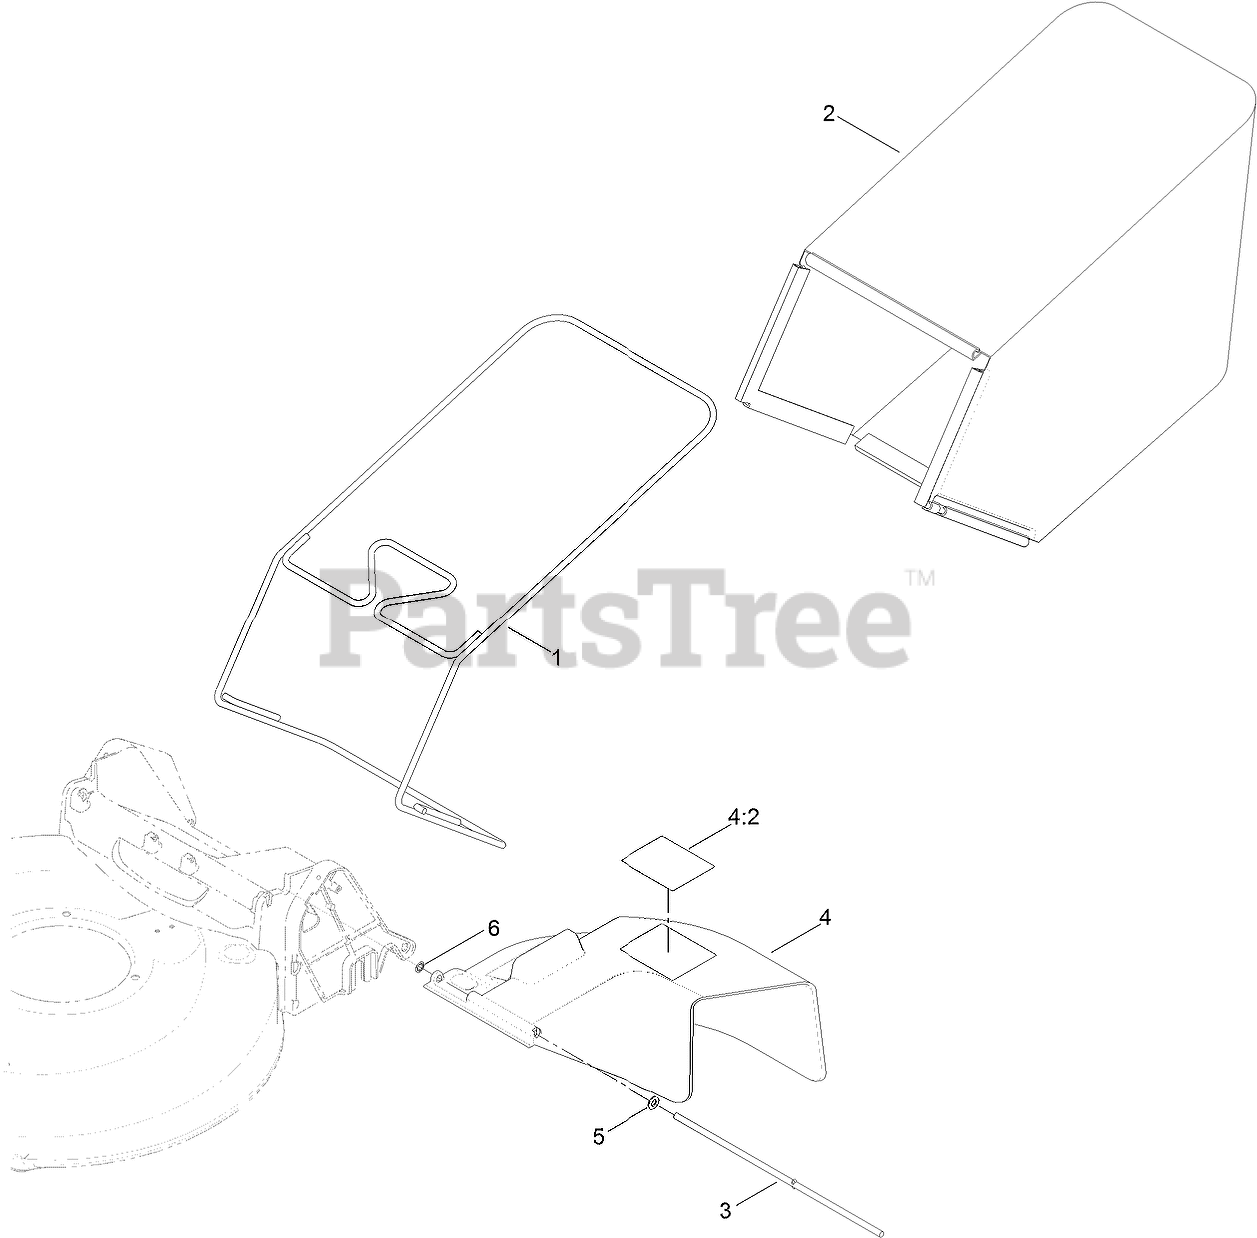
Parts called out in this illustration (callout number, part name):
1	FRAME-BAG
2	BAG-GRASS
3	ROD
4	DEFLECTOR-CHUTE
4:2	DECAL-WARNING
5	WASHER-PLAIN
6	RING-RETAINING
